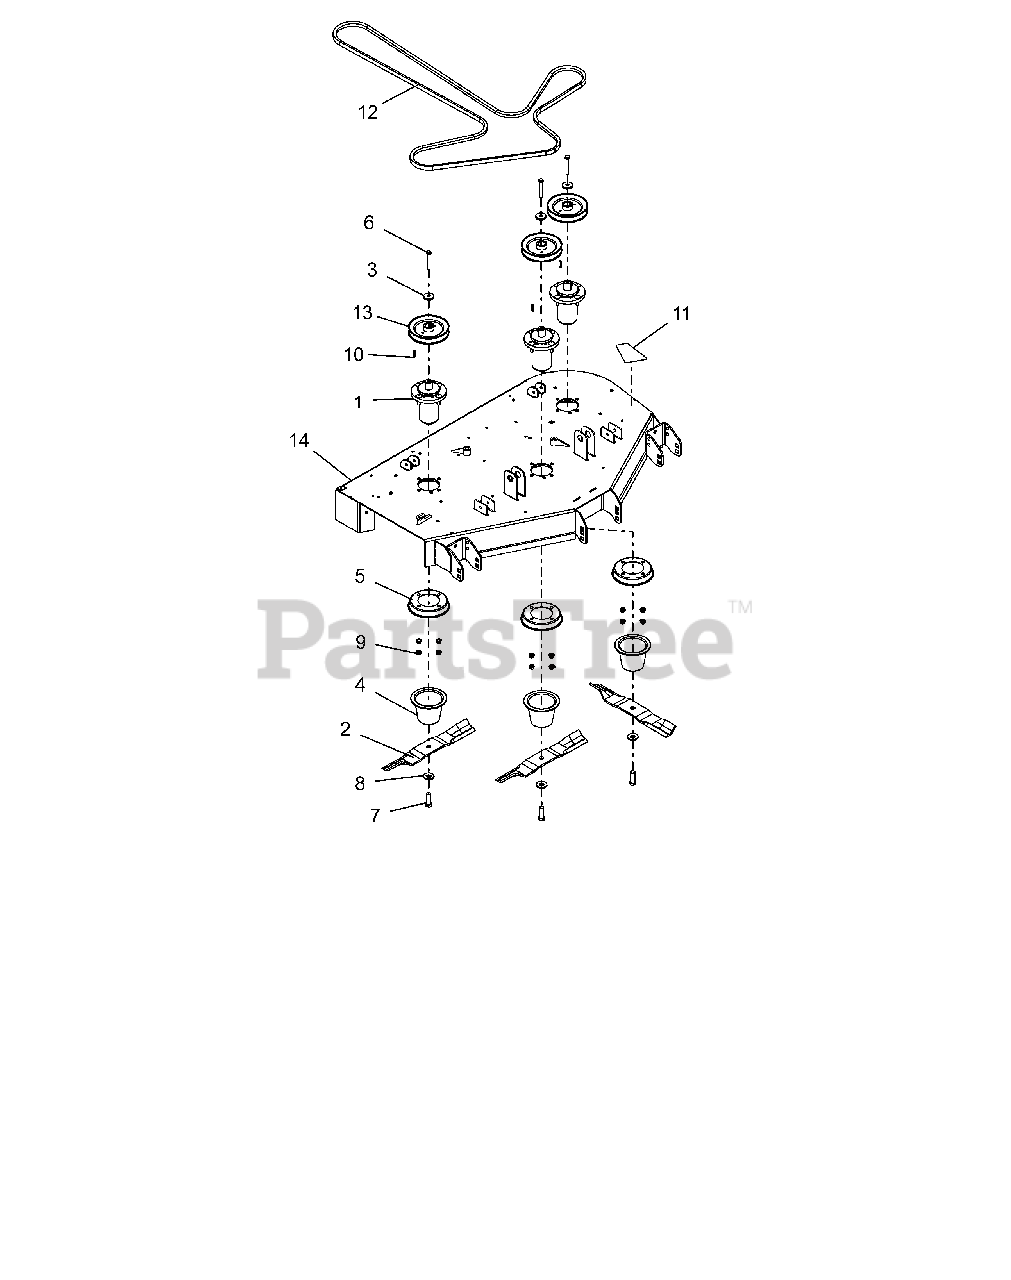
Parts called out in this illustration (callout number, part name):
1	ASM, MAINT FREE ALUM SPINDLE
2	BLADE, 16.19" MOWER (HI-LIFT)
3	RETAINER, SHEAVE
4	GUARD, SPINDLE LOWER
5	GUARD, SPINDLE TOP
6	BLT, HEX .38-16X2.75 G8 ZCC
7	BLT, HEX .62-18X1.75 G8 ZCC
8	WSHR-BLVL .669X1.535X.138
9	NUT-LK-CTR-FLG .375-16 GF ZCC
10	KEY, SQ .25X.25X1.00 RC 40-50
11	GRIP, STEP
12	V-BELT, B RAW EDGE EPDM
13	PULLEY, V-1.00 ID X 5.75 OD (BLACK)
14	KIT, 44" DECK W/SAFTEY DECALS
